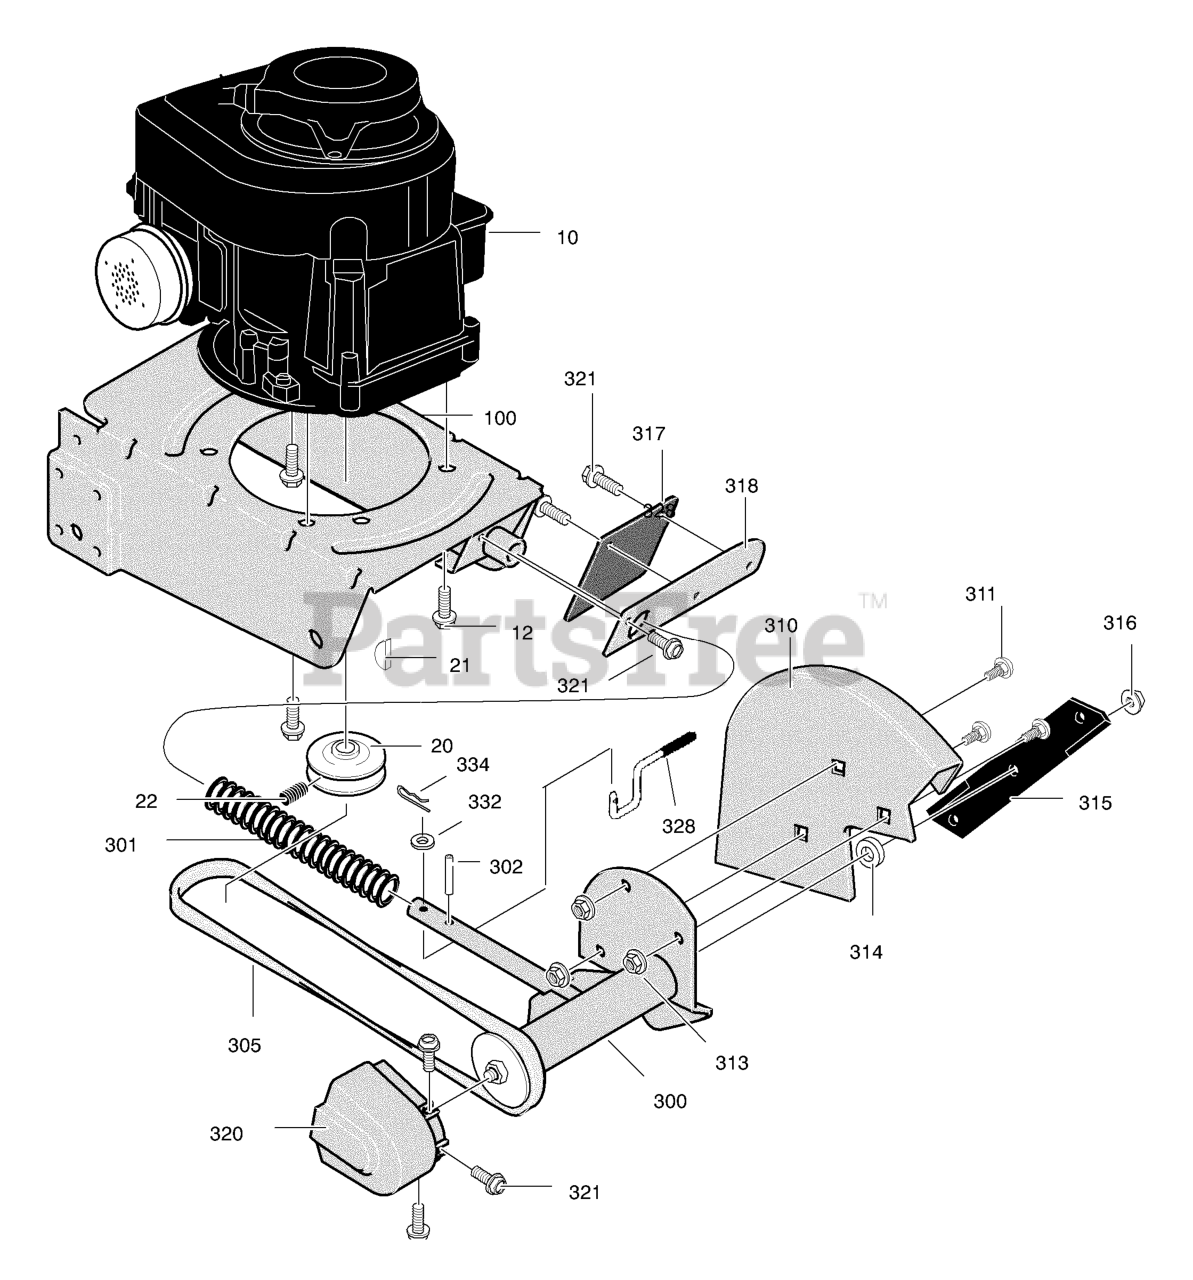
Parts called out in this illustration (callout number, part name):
10	Engine
20	Pulley, V3L
21	Key, Hi Pro #505
22	Screw, Set
100	Frame, Edger
300	Quill Assembly
302	Spring Pin
305	Belt, V4L
310	Blade Guard
311	Bolt, Carriage
313	Nut, 5/16-18
314	Flat washer
315	Blade, Edger
316	Nut, 1/2-20
317	Deflector, Rubber
318	Plate, Rubber Flap
320	Belt Guard
321	Screw, 10-16x.50
328	Lever, Blade
332	Washer
334	Pin, Hair
